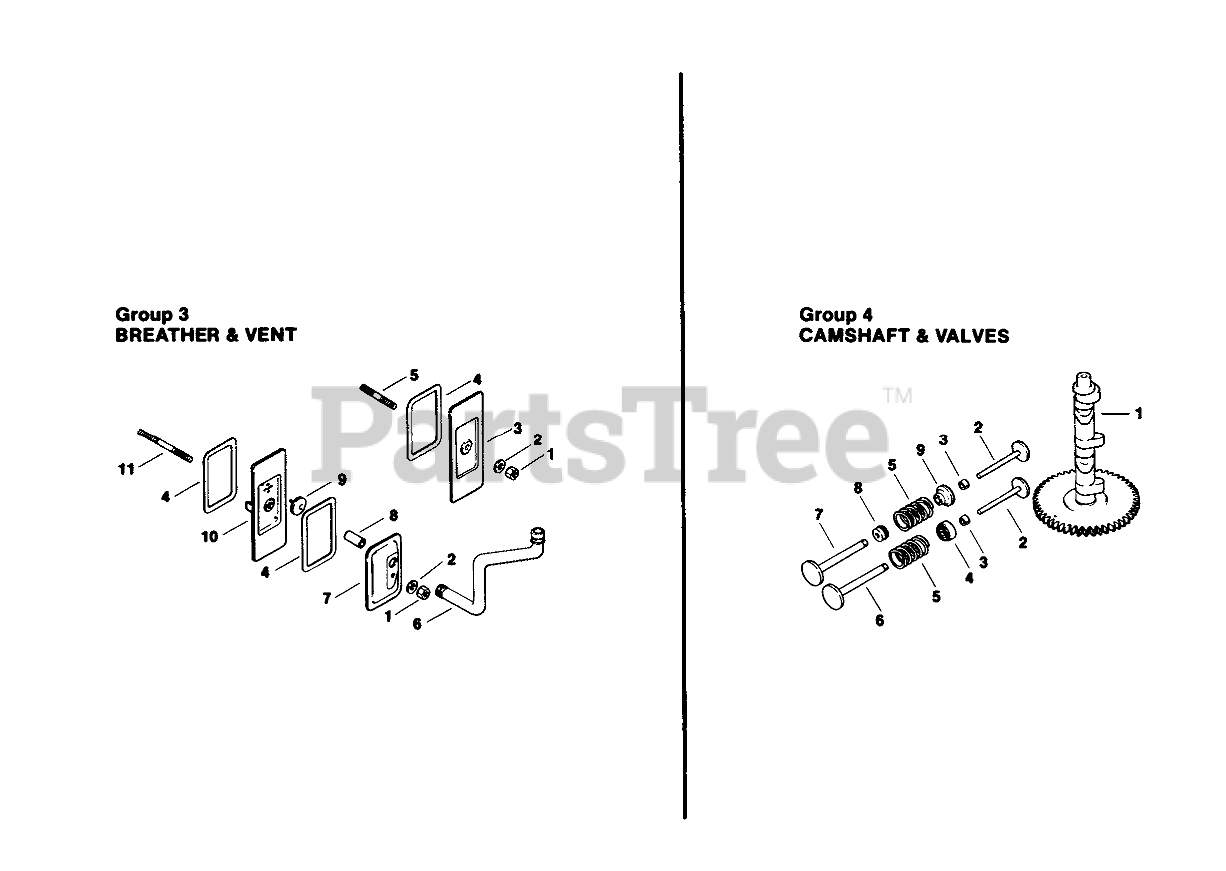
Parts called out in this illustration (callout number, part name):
1	Camshaft
2	Washer
3	Cover Cylinder Valve
3	Kit-Retainer
4	Gasket-Cover
4	Rotator-Valve
5	Stud-#2 Cyl Valve Cover
5	Spring-Valve
6	Hose-Breather
6	Valve-Exhaust
7	Cover-Upper Cylinder Valve
7	Valve-Intake
8	Seal-Breather
8	Seal-Intake Valve Stem
9	Valve-Umbrella
10	Cover-Lower Cylinder Valve
11	Locknut
11	Stud
